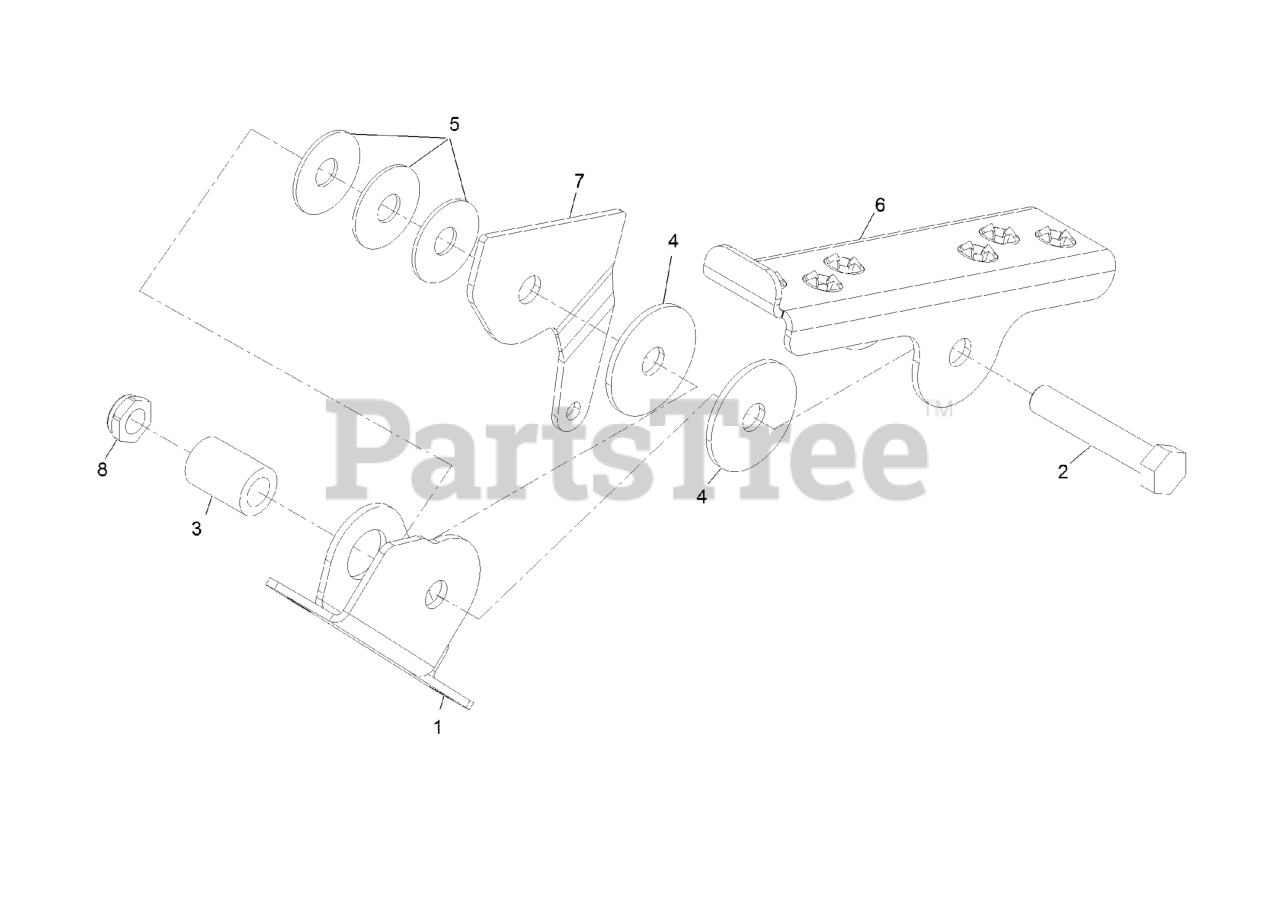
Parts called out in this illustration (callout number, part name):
1	BRACKET-PEDAL MOUNT
2	SCREW-HH
3	SPACER-ROLLER
4	DISC-FRICTION
5	WASHER-DISC, SPRING
6	CHANNEL,PEDAL LINK
7	ARM, FOOT PEDAL
8	NUT-HEX
